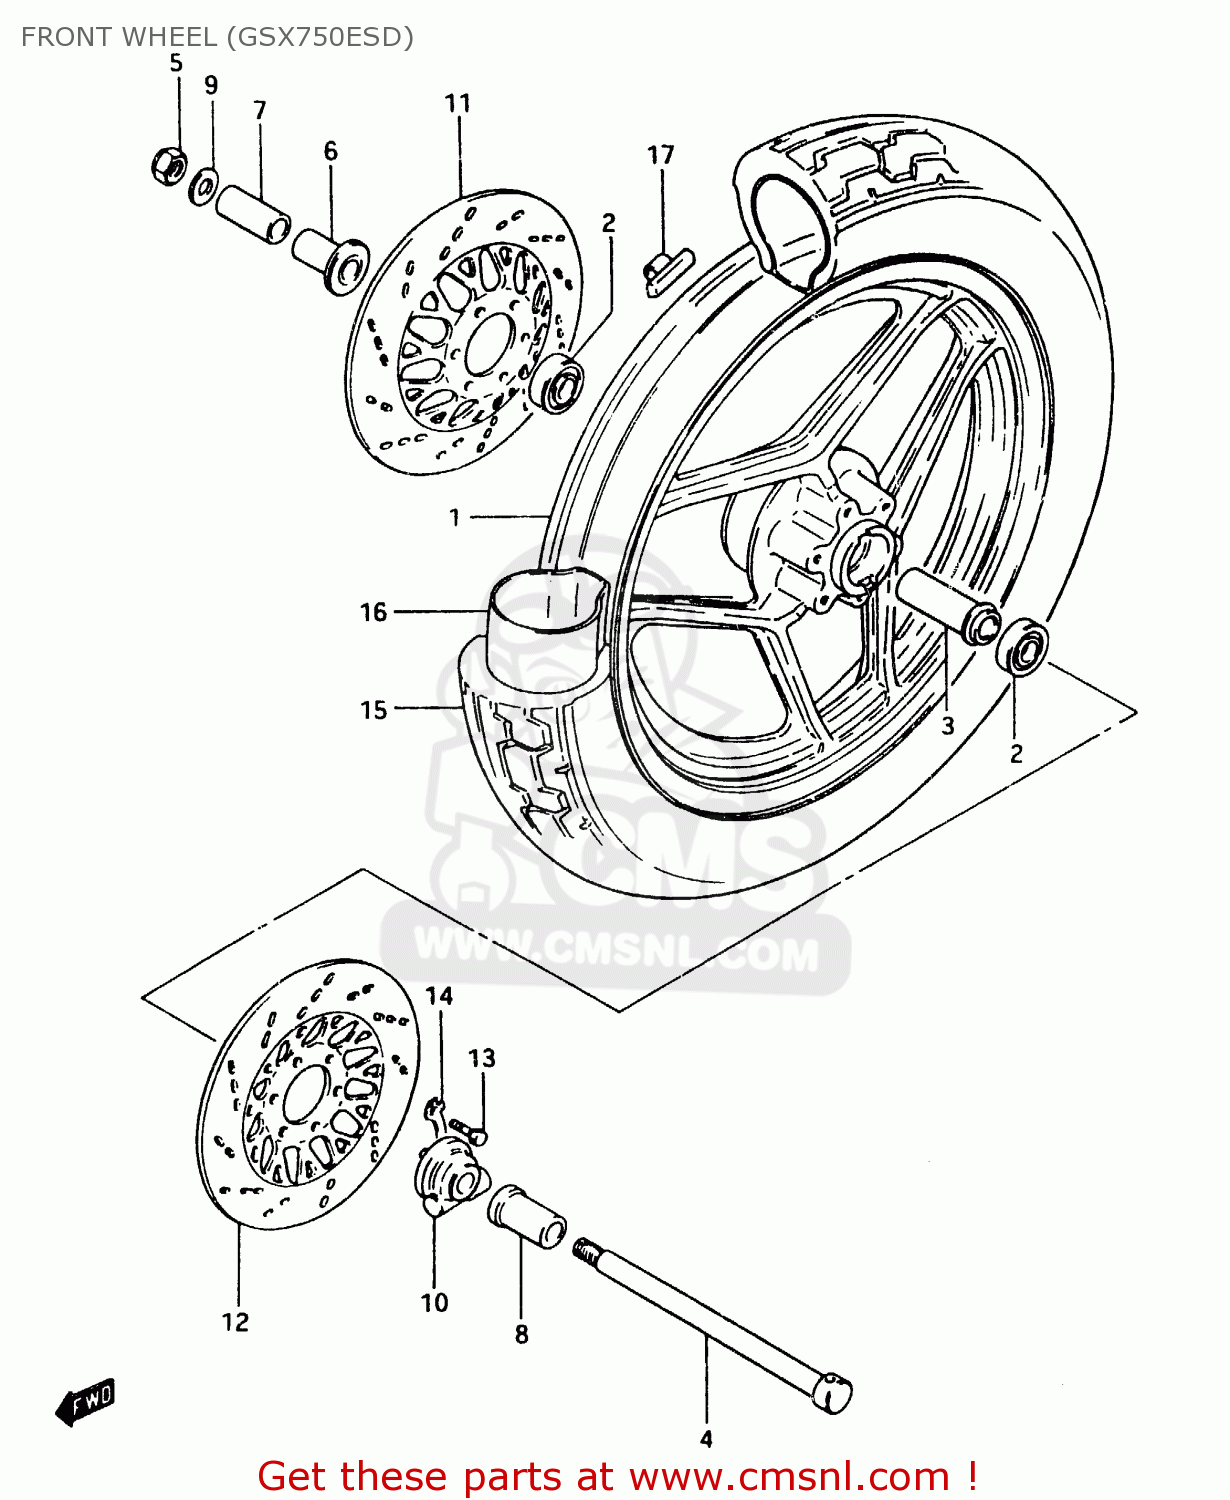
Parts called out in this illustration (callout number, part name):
1	WHEEL, FRONT (2.15X16)
2	BEARING
3	SPACER,FRONT HUB BEARING
4	AXLE,FR
5	NUT
6	SPACER,FR AXLE,R
7	SPACER,FR AXLE,R
8	SPACER,FR AXLE,L
9	WASHER
10	BOX ASSEMBLY,SPEEDOMETER GEAR
11	DISC,BRAKE,RIGHT
12	DISC,BRAKE,LEFT
13	BOLT(8X25)
14	WASHER
15	TIRE,FRONT
16	TUBE,INNER
17	BALANCER,WHEEL
